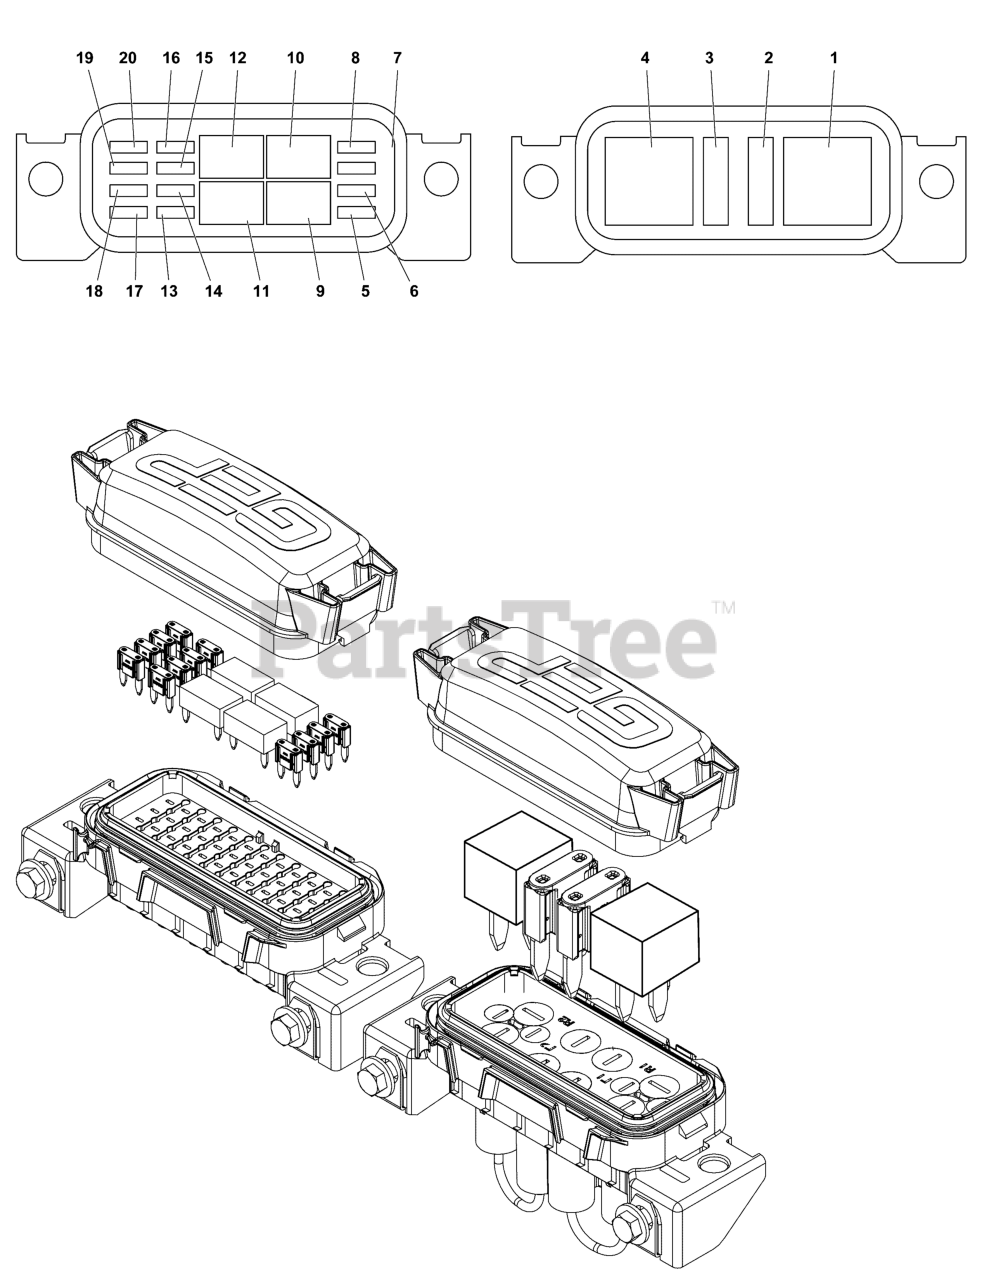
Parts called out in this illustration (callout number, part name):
1	RELAY,MAXI N/O DIODE PC795-1A-C-12C-DN-X
2	FUSE, MAXI 20 AMP 0299020
3	FUSE, 25 AMP
4	RELAY,MAXI N/O DIODE PC795-1A-C-12C-DN-X
5	FUSE, MINI 5 AMP 0297005
6	FUSE, MINI 10 AMP 0297010
7	FUSE, MINI 20 AMP 0297020
8	FUSE, MINI 5 AMP 0297005
9	RELAY
10	RELAY
11	RELAY
12	RELAY
13	FUSE, MINI 20 AMP 0297020
14	FUSE, MINI 20 AMP 0297020
15	FUSE, MINI 30 AMP 0297030
16	FUSE, MINI 5 AMP 0297005
17	FUSE, MINI 2 AMP 0297002
18	FUSE, MINI 5 AMP 0297005
19	FUSE, MINI 5 AMP 0297005
20	FUSE, MINI 10 AMP 0297010
